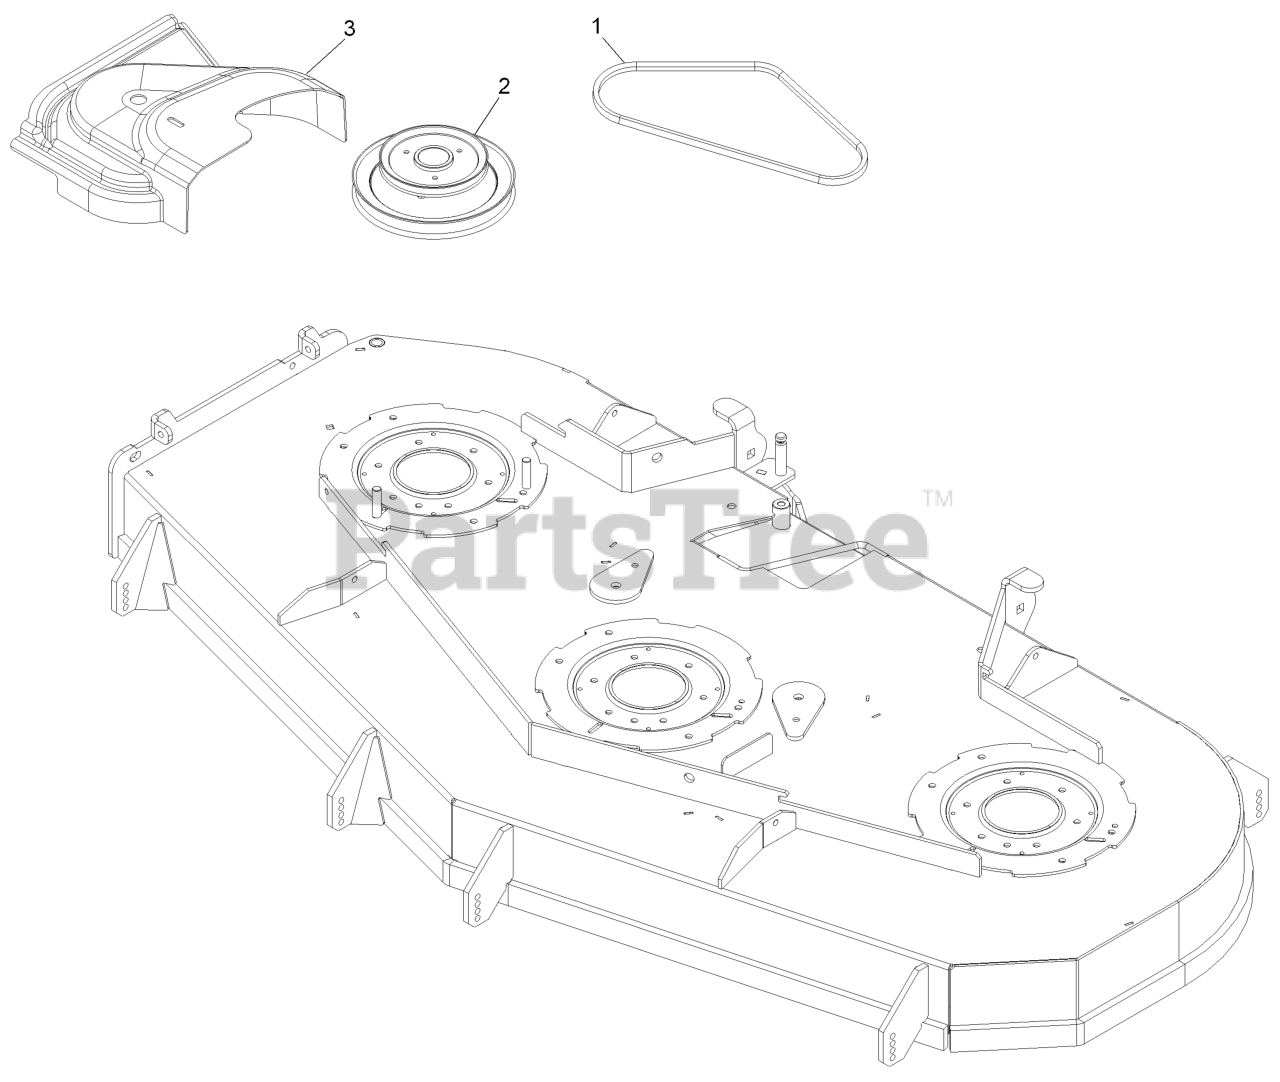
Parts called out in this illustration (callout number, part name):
1	BELT, BLOWER DRIVE 72
2	JACKSHAFT,UV DRIVE 724
3	COVER,BELT UV 72
